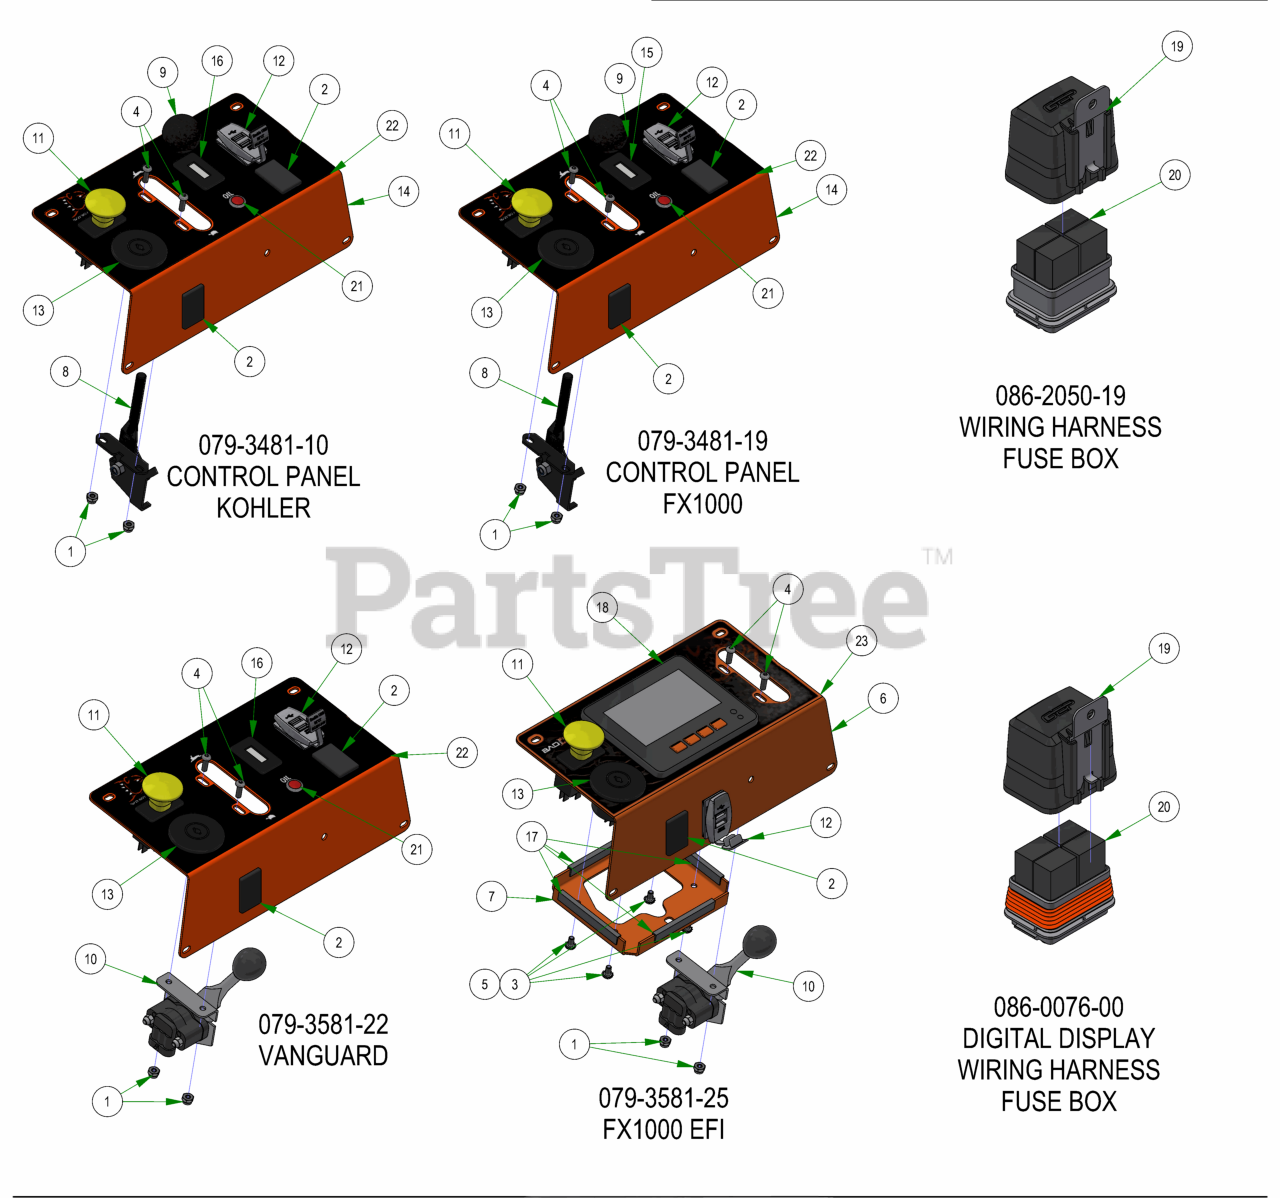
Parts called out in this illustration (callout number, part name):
1	10-24 NYLON INSERT LOCKNUT ZINC
2	Light Plug
3	10-32 X 3/8 BUTTON SOCKET CAP SCREW 18-8 STAINLESS STEEL
4	10-24 X 5/8 BUTTON SOCKET CAP SCREW 18-8 STAINLESS STEEL
5	18-8 Stainless Steel External-Tooth Lock Washer
6	Digital Display Control Panel
7	Digital Display Control Panel Backer
8	Universal Throttle Head - 2012
9	Throttle Knob
10	Kawasaki \ Kohler Drive By Wire
11	PTO Switch
13	Ignition Switch
14	2022 Rebel Control Panel
15	Tachometer
16	Tachometer
17	SBR Rubber Trim
18	2025 Display Screen
19	Relay Block Cover Replacement Kit
22	2022 Rebel/Rogue Control Panel Decal
23	2025 Rogue Digital Display Control Panel Decal
